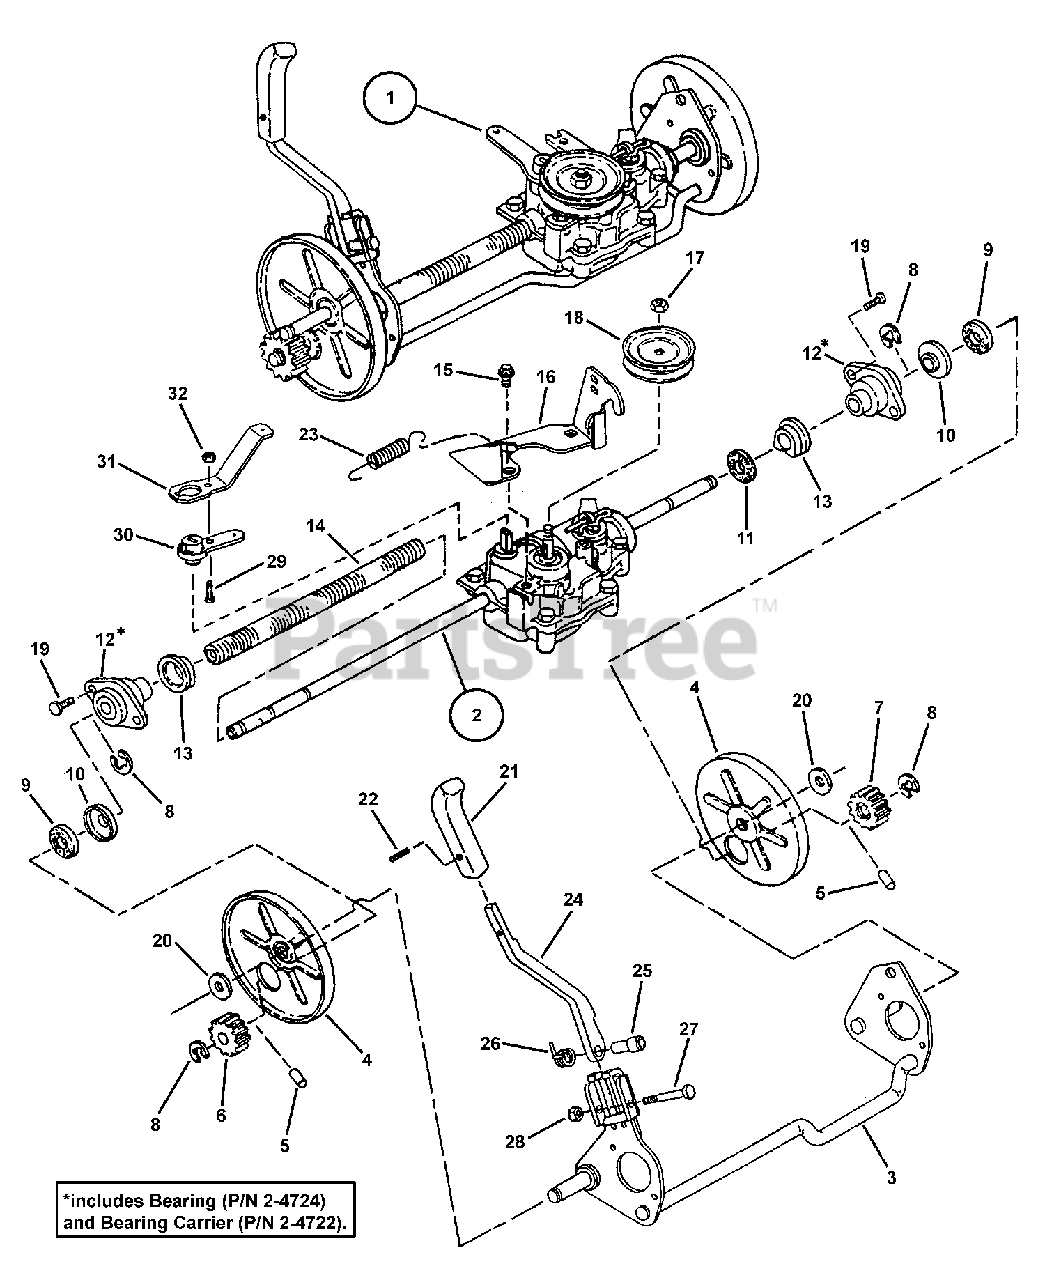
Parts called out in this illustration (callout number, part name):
1	ASSEMBLY, Axle/Transmission
2	ASSEMBLY, Transmission, 3-Speed Commercial
3	WELDMENT, Rear Axle
4	SHIELD, Dust
5	PIN, Pawl, 3/16" Outside Diameter
6	PINION, Right Hand Drive
7	PINION, Left Hand Drive
8	RING, External Retaining
9	SEAL, Pinion (Felt)
10	RETAINER, Pinion Seal
11	WASHER, Felt
12	ASSEMBLY, Bearing Carrier
13	BUSHING, Rear Axle (S/P)
14	TUBING, 5/8 I.D. Convoluted
15	SCREW, 5/16-18 x 5/8" Hex Washer Head, Self-Tap
16	BRACKET, Transmission
17	NUT, M10 x 1.50 Hex Nyloc
18	PULLEY, Transmission
19	SCREW, 1/4-20 x 3/8" Hex Washer Head, Self-Tap
20	WASHER, 17/32 I.D. x 1-1/2" O.D.
21	KNOB, Height Adjusting Lever
22	ROLL PIN, 3/16 x 3/4"
23	SPRING, Clutch
24	HANDLE, Height Adjustment
25	SPACER, .37 x .5 x .44
26	SPRING, Return, Commercial
27	SCREW, 1/4-20 x 2" Hex Head Cap GR5
28	NUT, 1/4-20 Hex Nyloc
29	SCREW, #10-24 x 5/8" Slotted Hex Washer Head Self-Tap
30	ARM, Shift
31	LEVER, Transmission (Metal)
32	NUT, #10-24 Hex Center Lock
